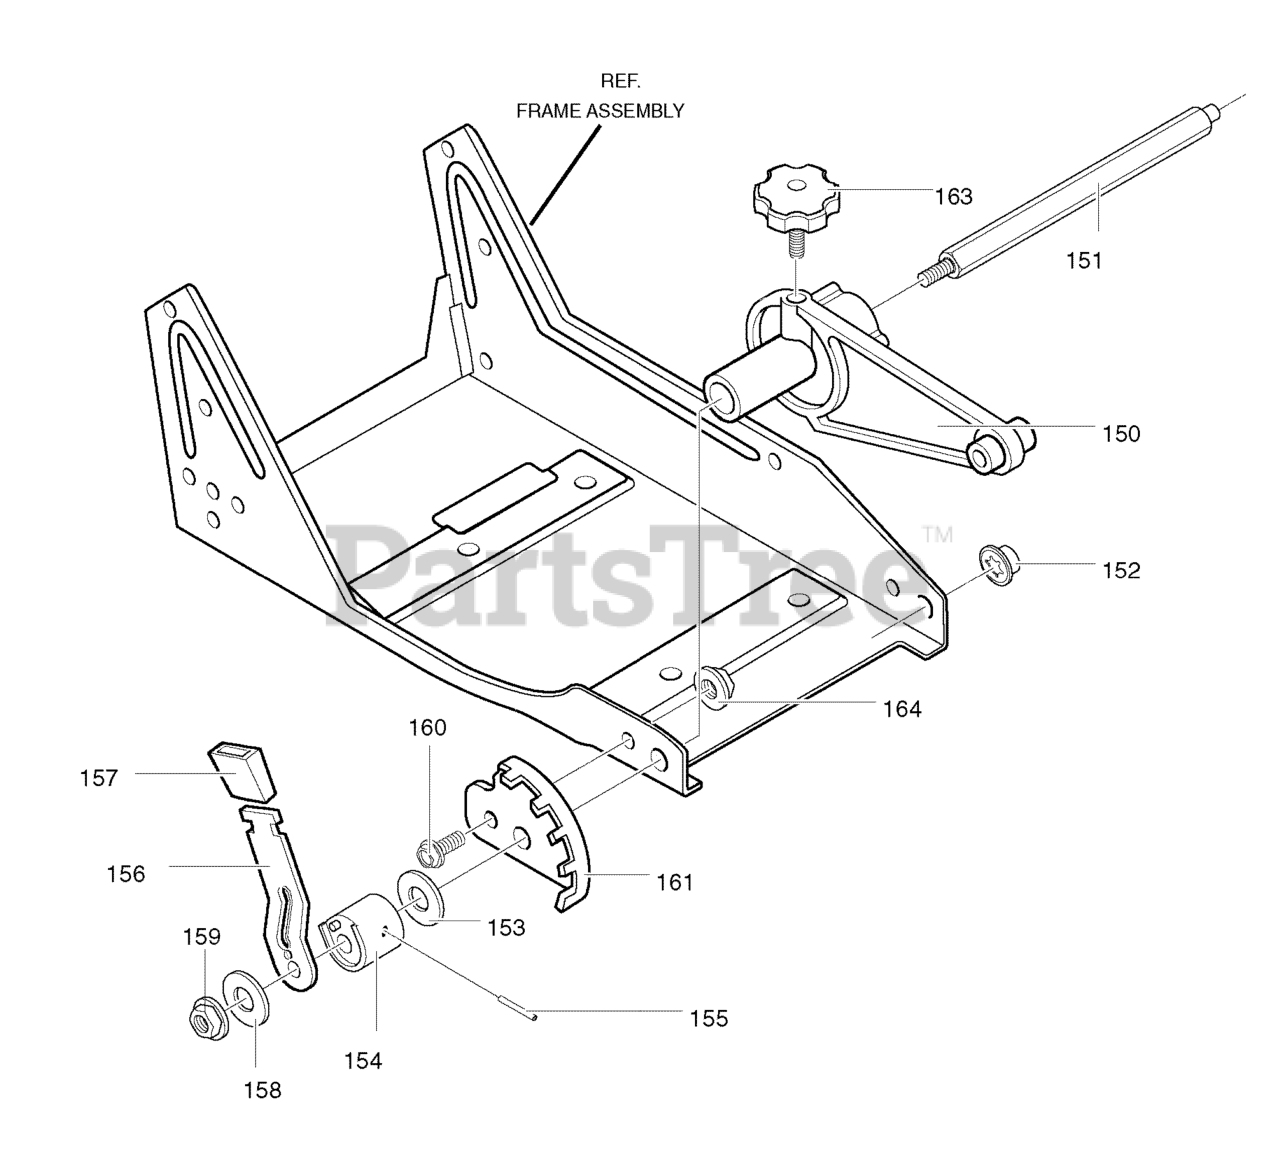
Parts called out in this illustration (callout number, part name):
150	ARM, Front Wheel
151	ROD, Front Mount Curb
152	PUSHNUT, Washer
153	WASHER, Plastic
154	SPACER, Height Adjust
155	PIN, Spring
156	LEVER, Height Adjust
157	KNOB, Rectangle
158	FLATWASHER
160	SCREW, 5/16-18 x 0.63
161	PLATE, Height Adjust
163	KNOB, Molded
164	NUT, 5/16-18
